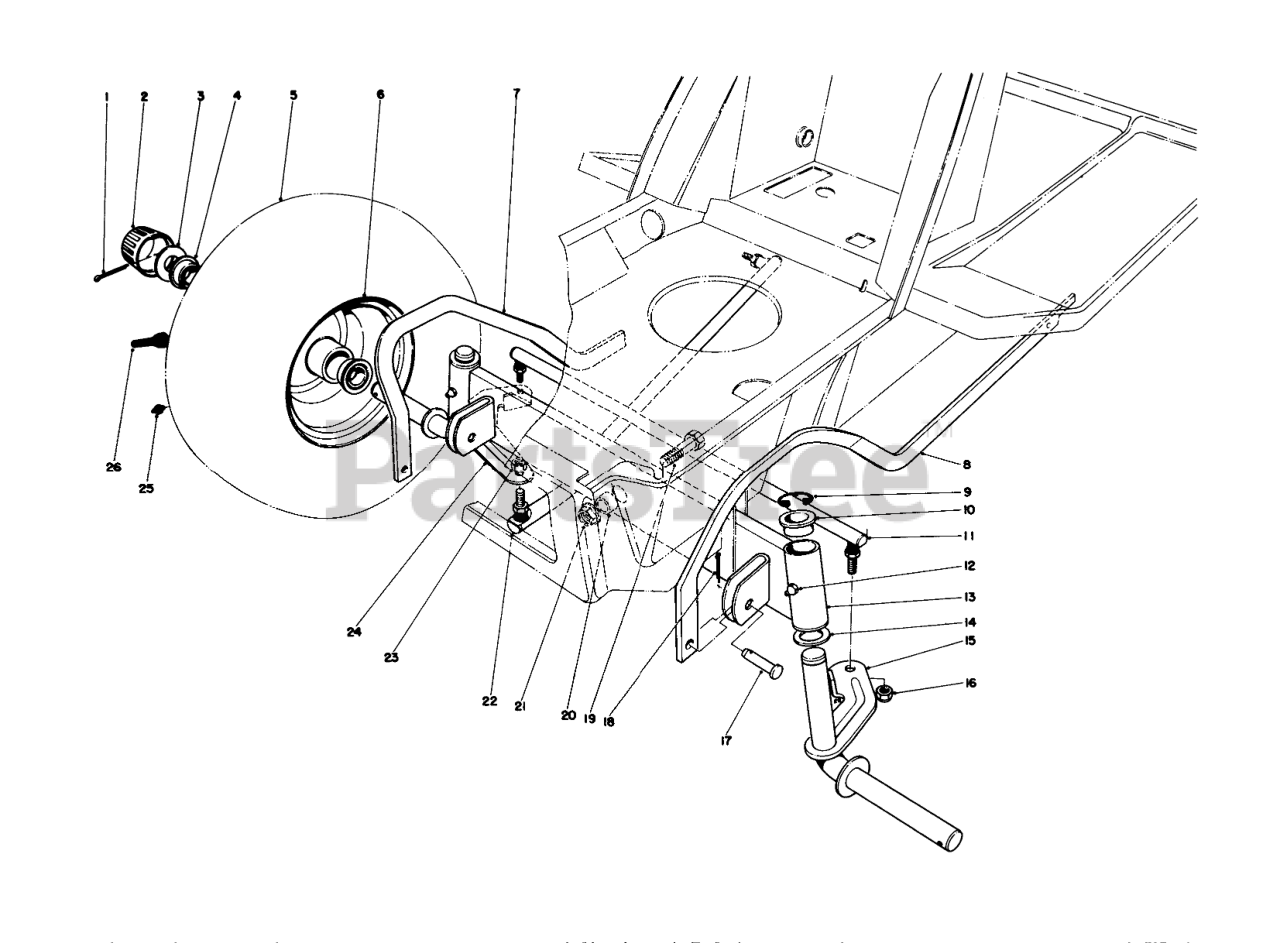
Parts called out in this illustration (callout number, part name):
1	PIN-COTTER
2	Cap-Hub
3	WASHER-PLAIN
4	Bearing
5	TIRE-FRONT
6	FRONT WHEEL
7	RH DECK PARALLEL LINK R
8	LH DECK PARALEL LNKR
9	E-RING
10	BEARING-FLANGE
11	Tie Rod Steering
12	GREASE FITTING
13	Front Axle (Incl . Ref. . #10)
14	WASHER-THRUST
15	Spindle L.H.
16	NUT-LOCK NI
17	PIN-CLEVIS
18	PIN-COTTER
19	SCREW-HH
20	SPACER-AXLE, FRONT
21	NUT-HF
22	Steering Arm
23	Nut
24	SPINDLE WA RH B
25	FITTING-GREASE
26	STEM-VALVE
